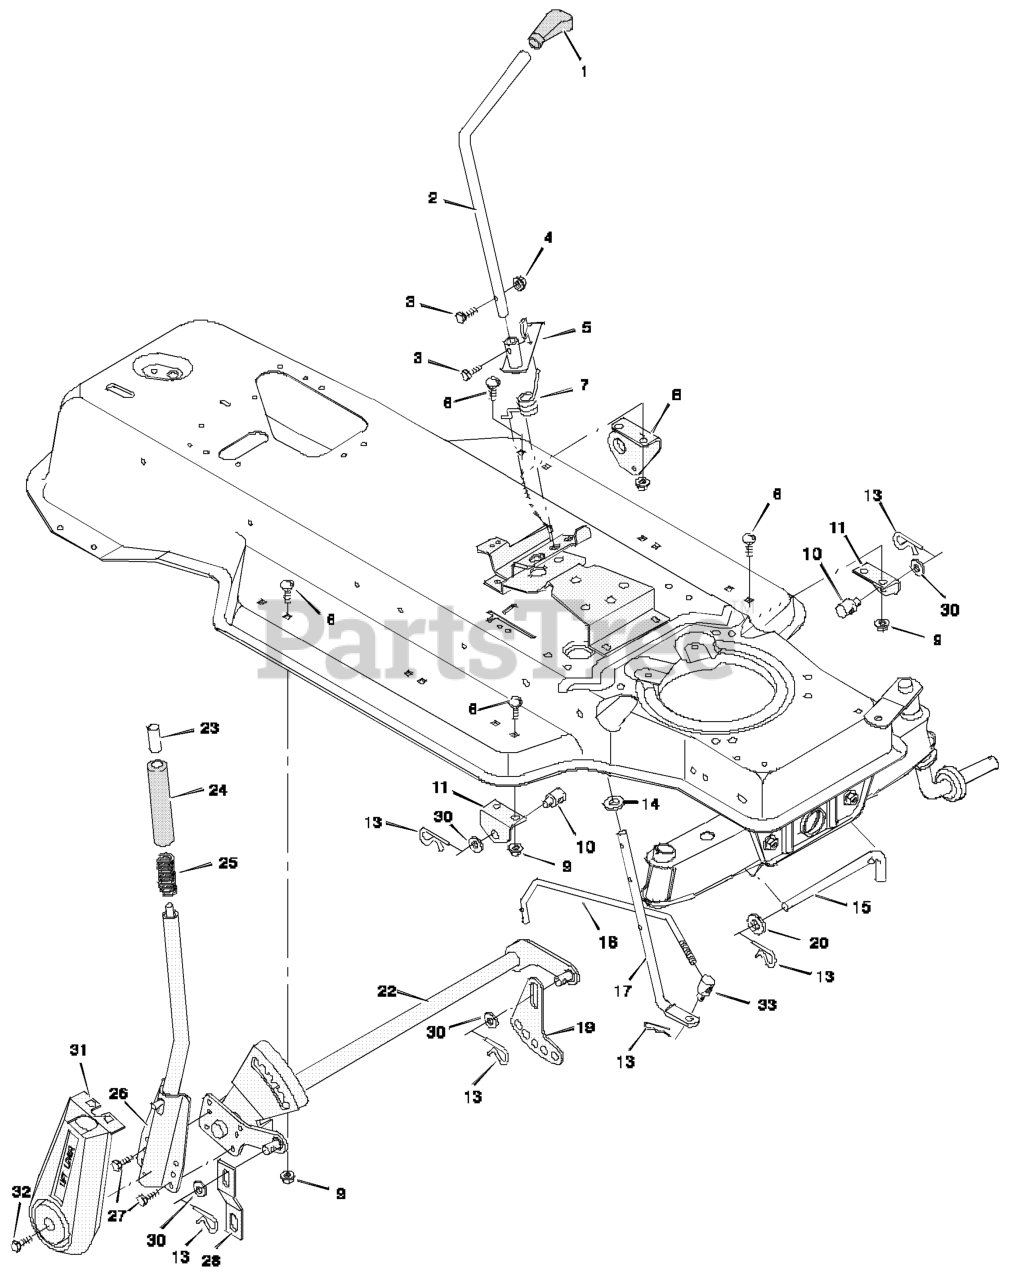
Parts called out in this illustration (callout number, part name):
1	Grip
2	Control, Blade Rotation
3	Screw, Hex
4	Locknut, Hex
5	Lever Assembly, Switch
6	Bolt, Carriage
7	Spring, Torsion
8	Bracket, Rear Hanger
9	Nut, Flange
10	Nut, Adjusting
11	Bracket, Adjuster Rod
13	Pin, Hair
14	Washer
15	Pin, Pull
17	Lever, Lower Blade Control
18	Rod, Blade Control
22	Litter Assembly
23	Button, Push
25	Spring, Compression
26	Handle Assembly
31	Cover, Lift Lever
33	Nut, Adjusting
